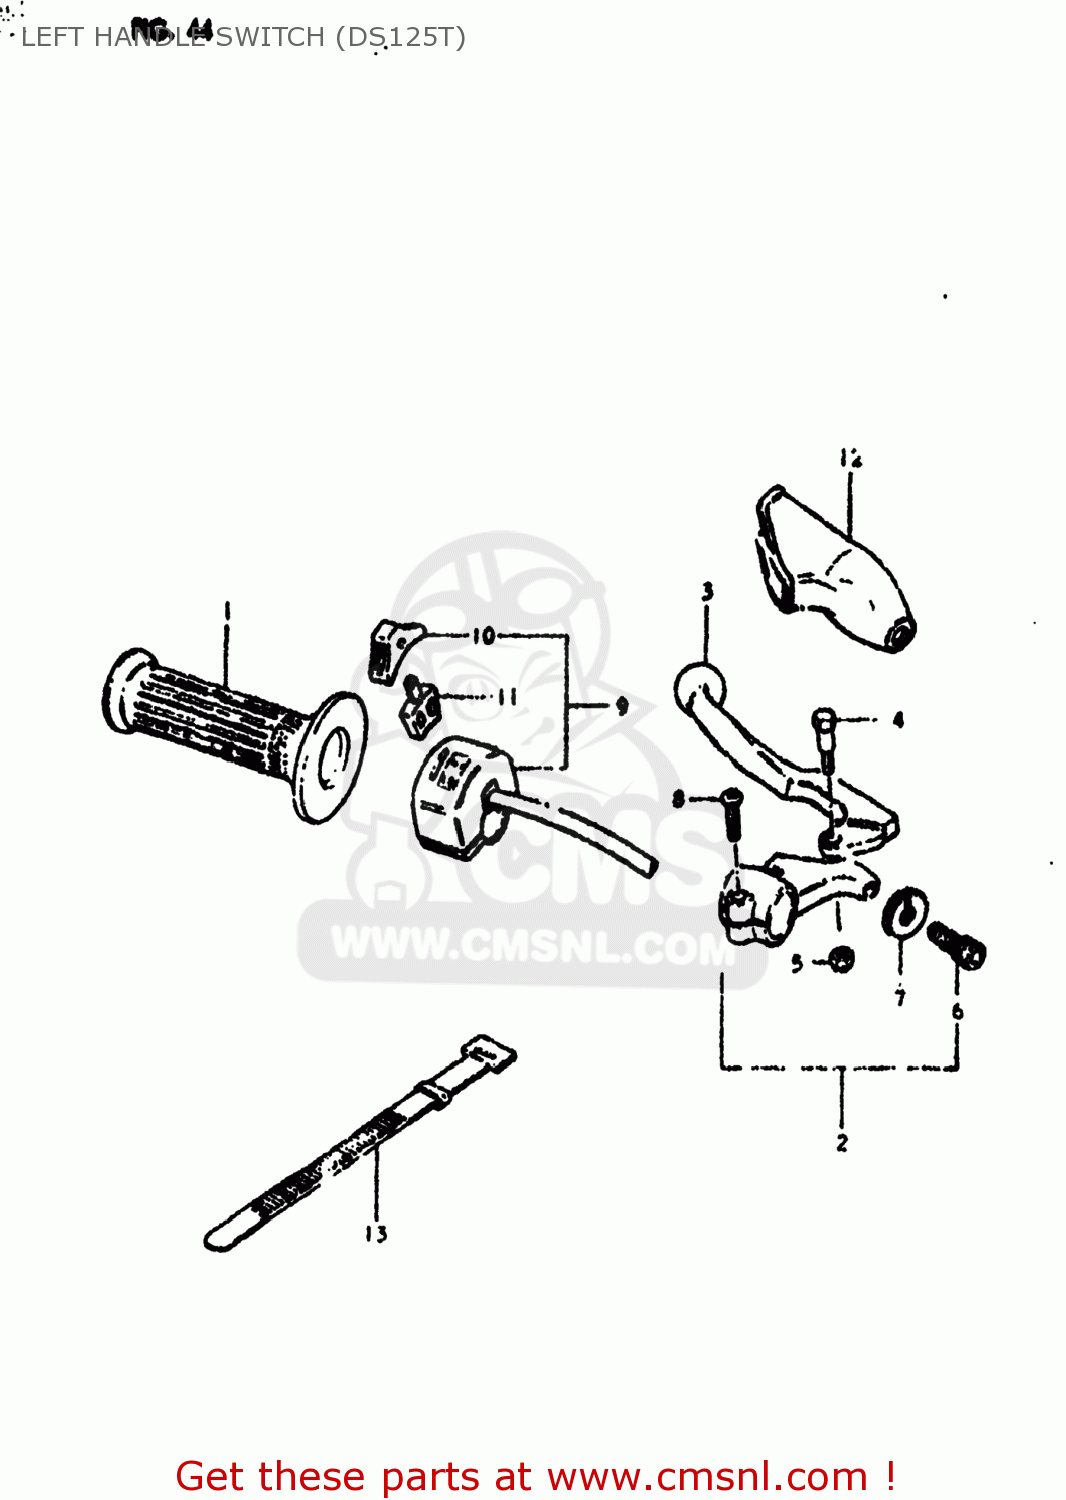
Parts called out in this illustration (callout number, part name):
1	GRIP,L
2	LEVER ASSEMBLY,CLUTCH
3	LEVER,CLUTCH
4	BOLT,LEVER
5	NUT
6	ADJUSTER,CABLE
7	NUT,CABLE ADJUSTER
8	SCREW
9	SWITCH,DIMMER
10	KNOB,LIGHTING & DIMMER
11	BLOCK,LIGHTING/DIMMER
12	COVER,CLUTCH LEVER
13	CLAMP(L:120)
